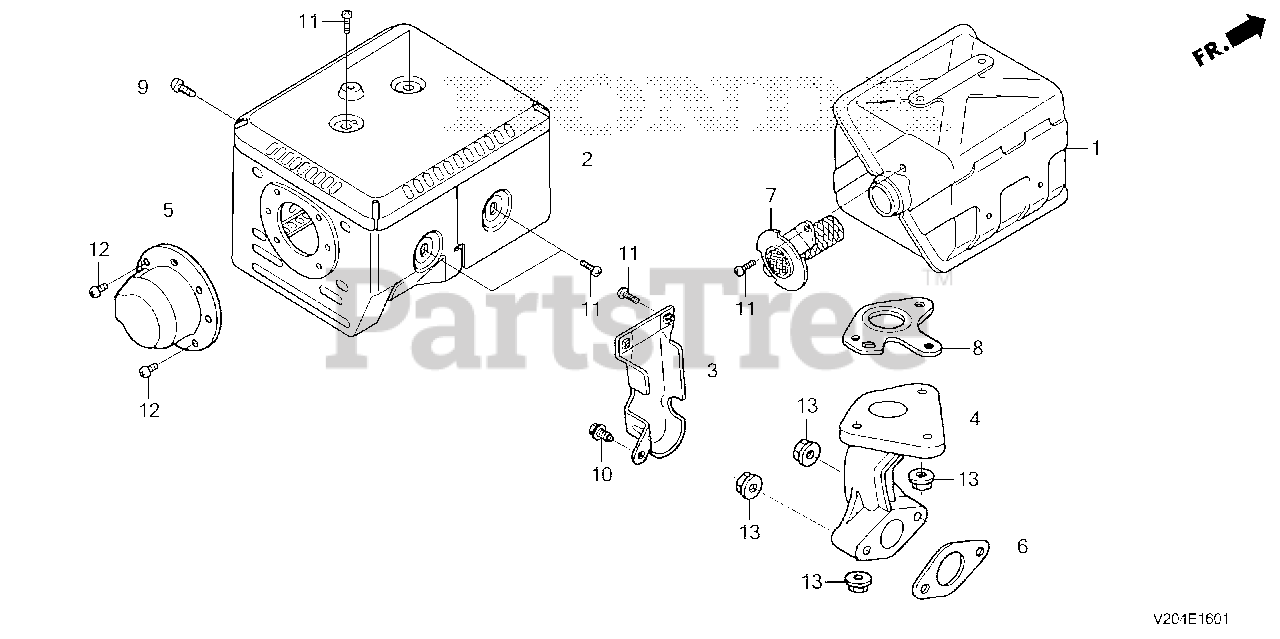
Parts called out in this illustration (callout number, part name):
1	MUFFLER
2	PROTECTOR, MUFFLER
3	PROTECTOR, EX. PIPE
5	CAP, MUFFLER
6	GASKET, EX. PIPE
7	ARRESTER, SPARK
8	GASKET, MUFFLER (ARRESTER) (NIPPON LEAKLESS)
8	GASKET, MUFFLER (ARRESTER)(THAI LEAKLESS)
9	SCREW, TAPPING (6X10)
10	BOLT, FLANGE (6X12) (CT200)
11	SCREW, TAPPING (5X8)
12	SCREW, TAPPING (4X6)
13	NUT, FLANGE (8MM)
